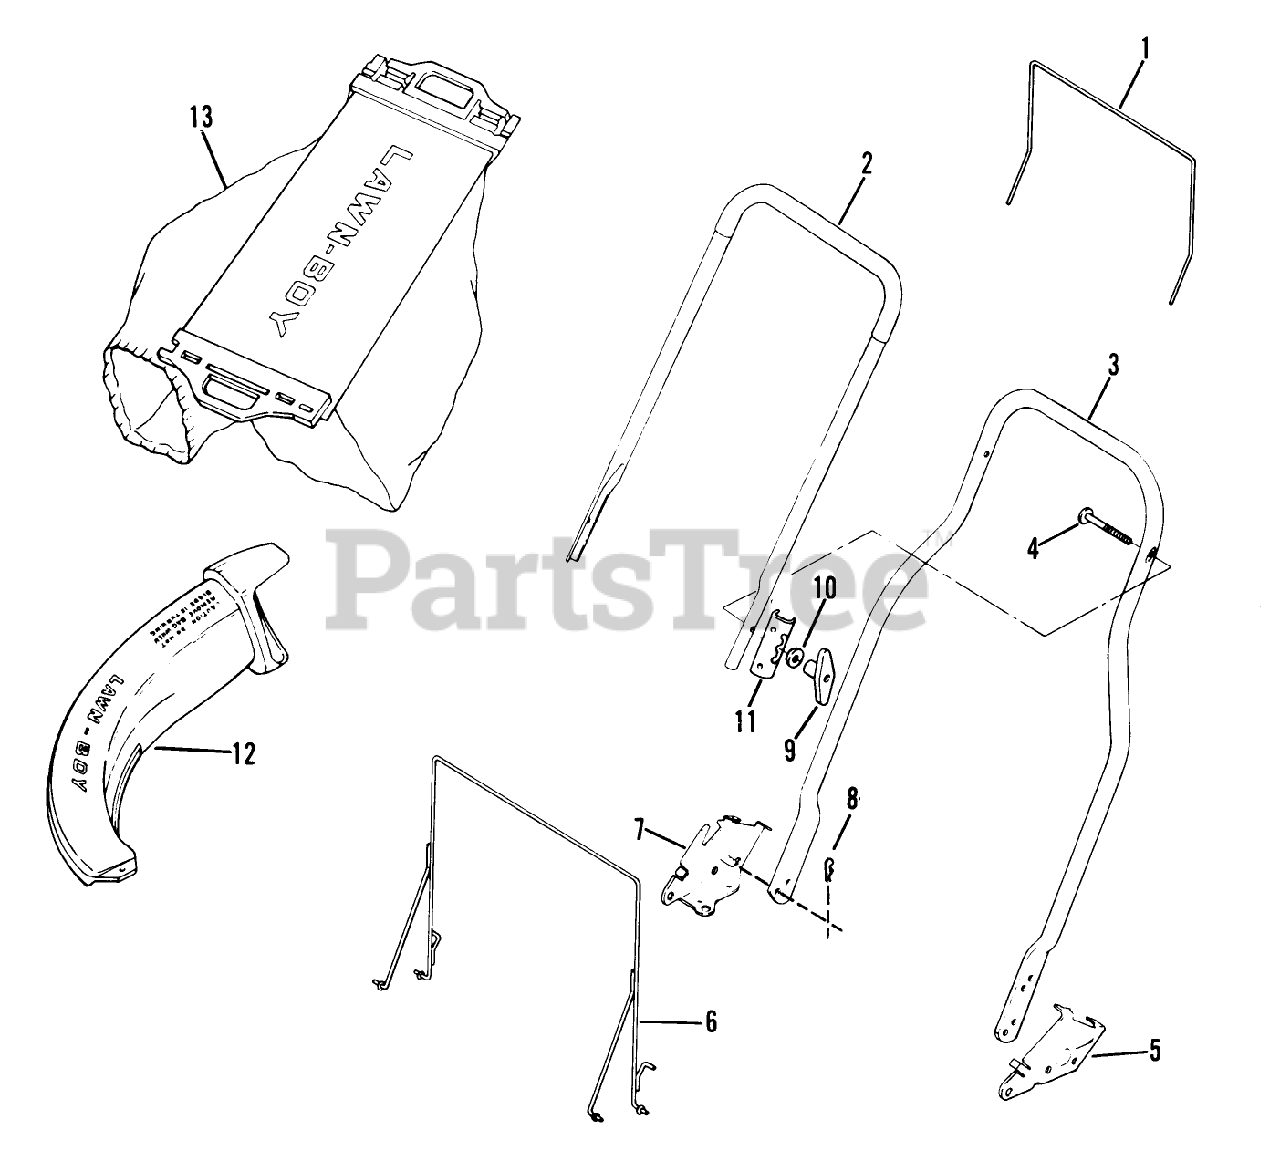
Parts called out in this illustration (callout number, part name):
8	HAIR PIN
9	NUT-WING
10	WASHER-CURVED
11	BRACKET R/B 613462
